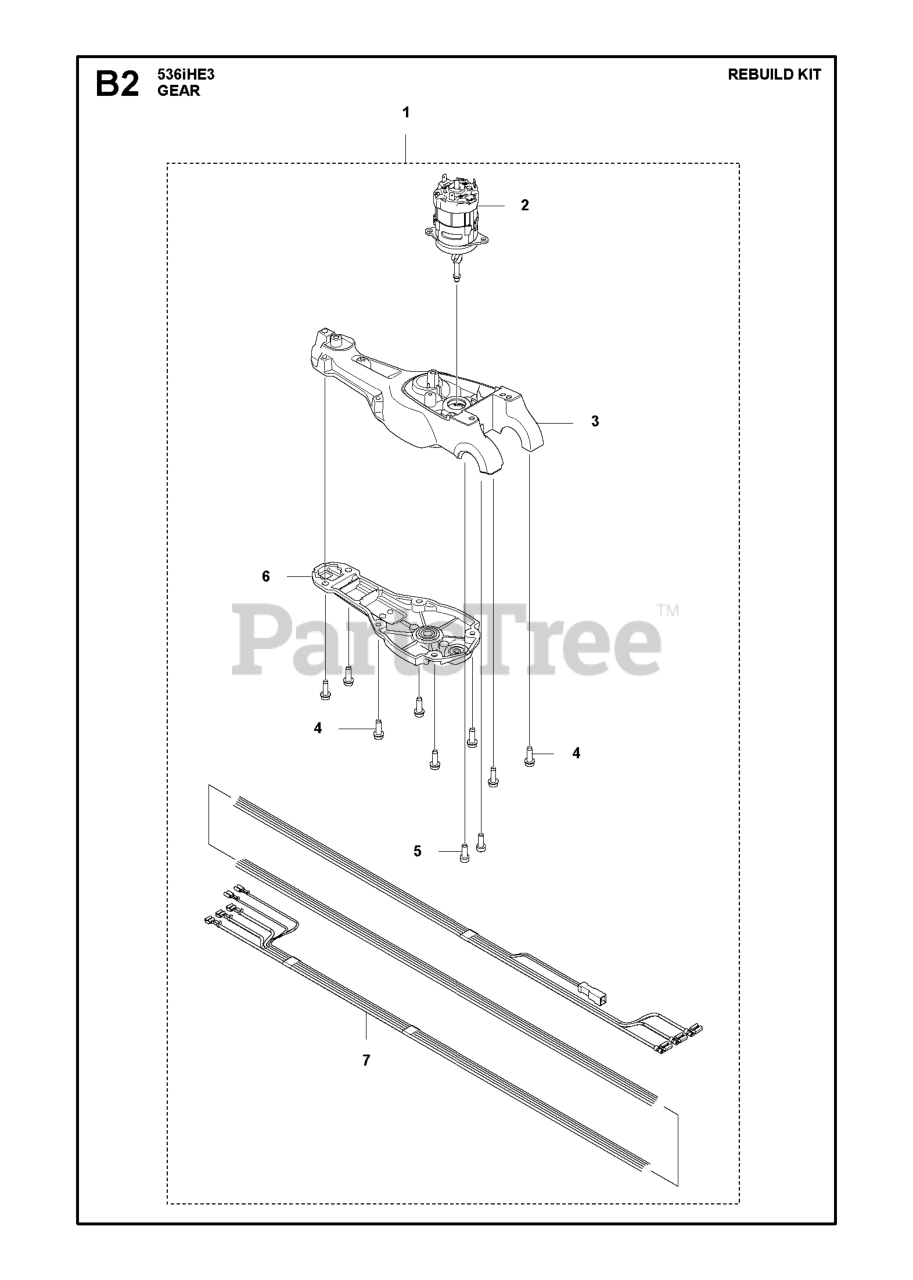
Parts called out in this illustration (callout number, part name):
4	SCREW
5	SCREW MC6S 5X16
7	WIRING ASSY POLE HEDGE MOTOR B
